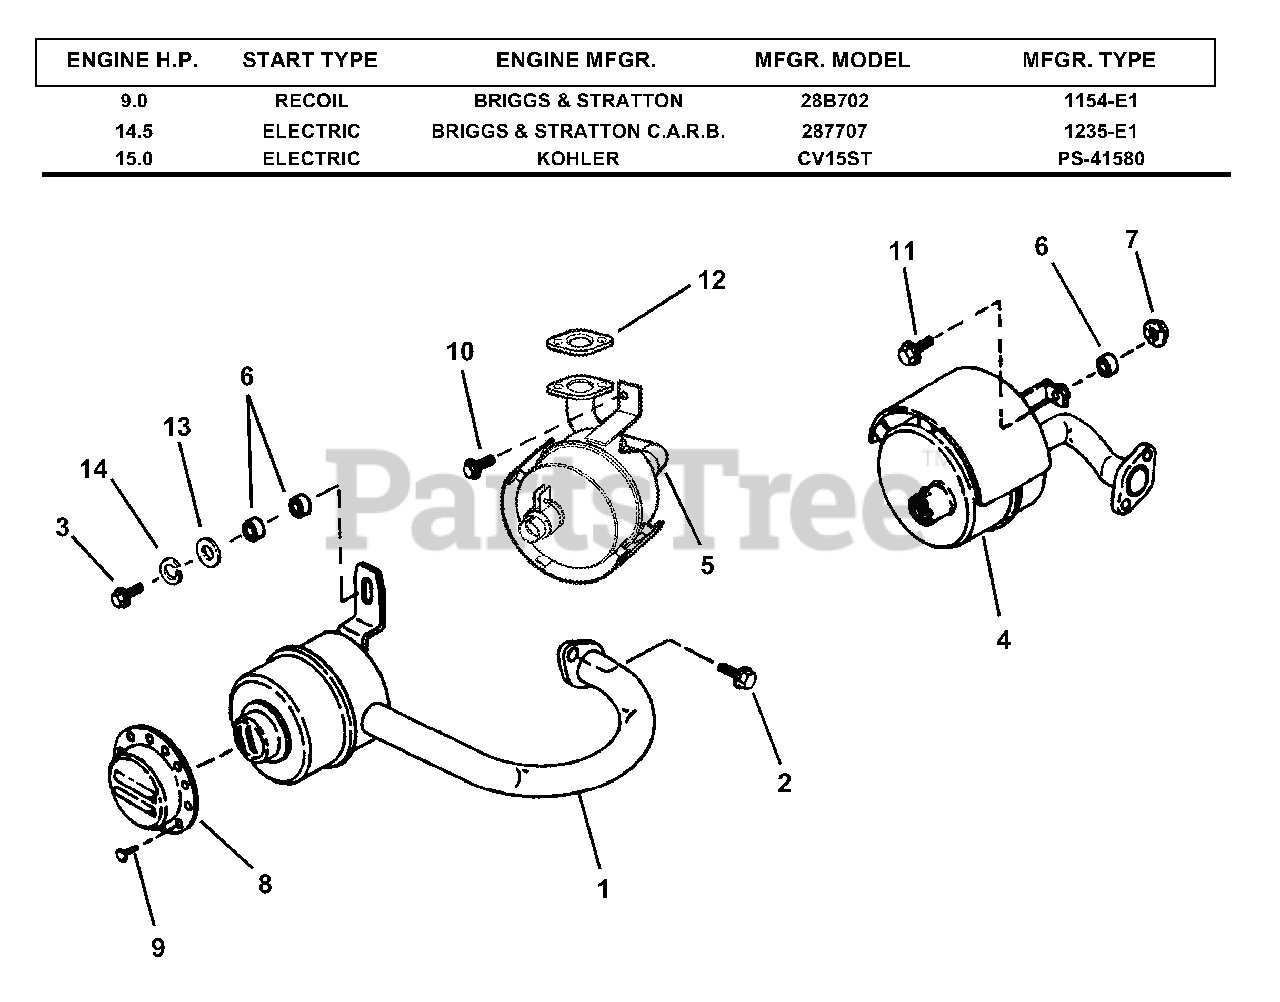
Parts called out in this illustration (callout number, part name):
1	MUFFLER
2	SCREW, 5/16-18 x 3/4" Hex Head Cap, Grade 2
3	SCREW, 1/4-20x1-1/4" Hex Head Cap
4	MUFFLER
5	MUFFLER
6	SPACER
7	NUT, 1/4-20 Hex Flange Lock
8	DEFLECTOR, Heat
9	SCREW #8-18 x 3/8" Type AB Modified
10	SCREW, 1/4-20 x 5/8" Hex Washer Self-Tap
11	SCREW, 1/4-20 x 3/4" Hex Head Cap, Grade 5
12	GASKET, Muffler
13	WASHER, 1/4" Flat
14	WASHER, 1/4" Split Lock
